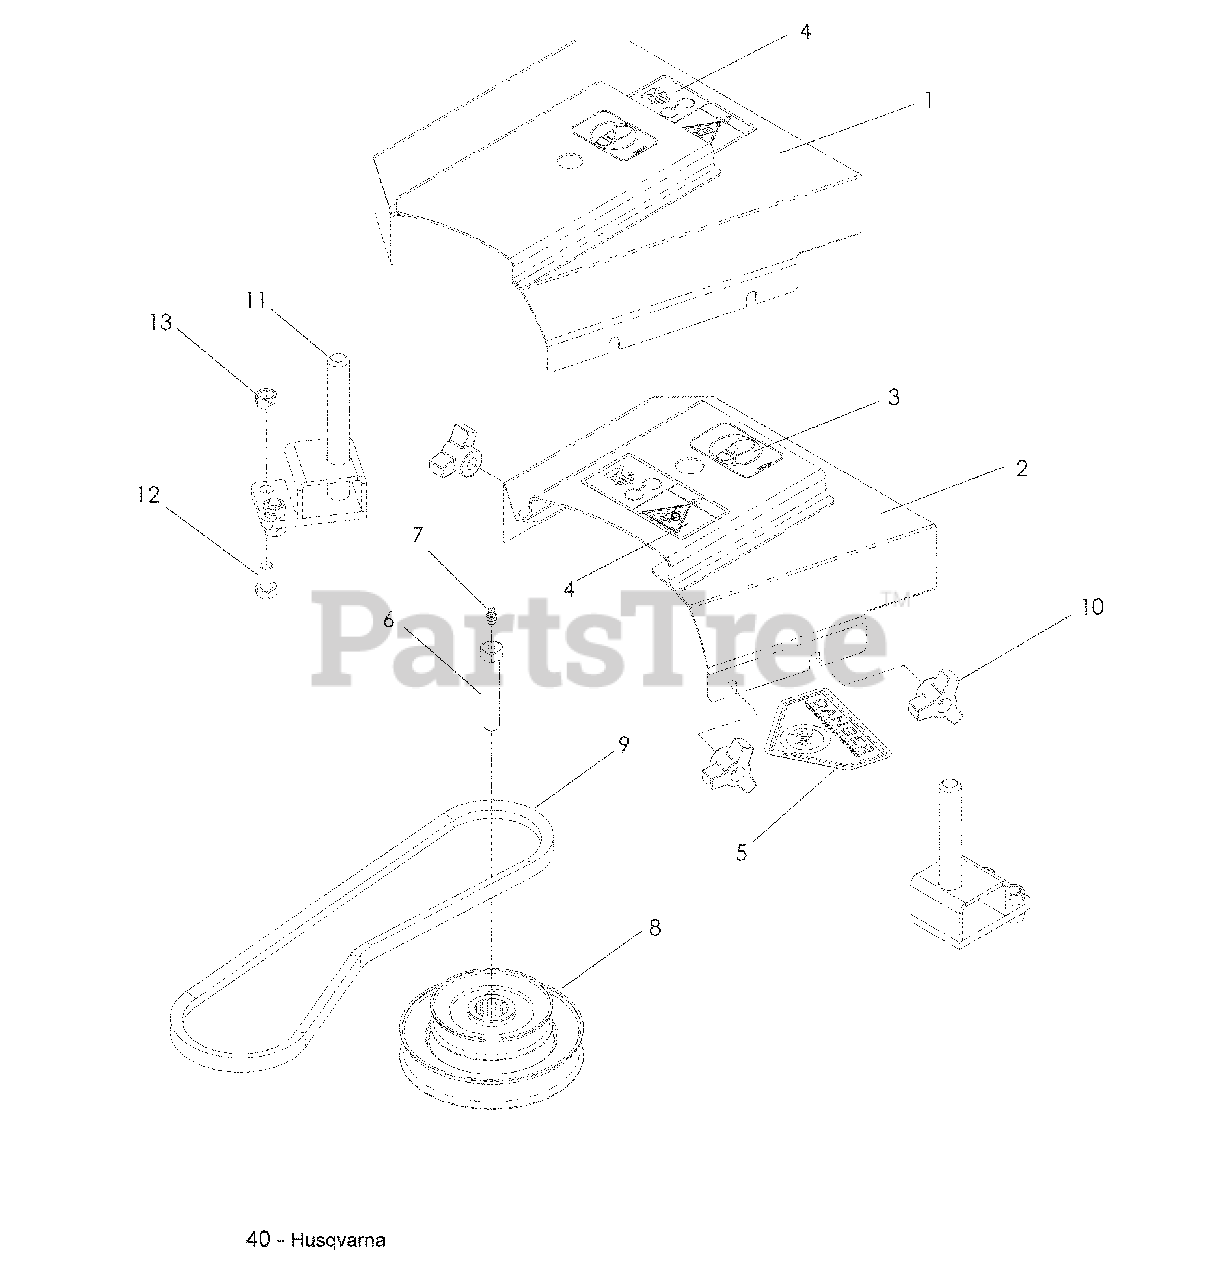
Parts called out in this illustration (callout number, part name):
1	SHIELD W/DECALS 52"
2	SHIELD W/DECALS 61"
3	DECAL, NO STEP
4	DECAL, DANGER BELT DR
5	DECAL, CPSC
6	HCS 7/16-20 x 2½ SPECIAL
7	ZERK
8	PULLEY, DBL, STACKED, 52"
10	KNOB, THREE PRONG
11	BLOWER PIN, SM
12	HCS 3/8-16 x ¾
13	NUT 3/8 -16 CENTERLOCK
